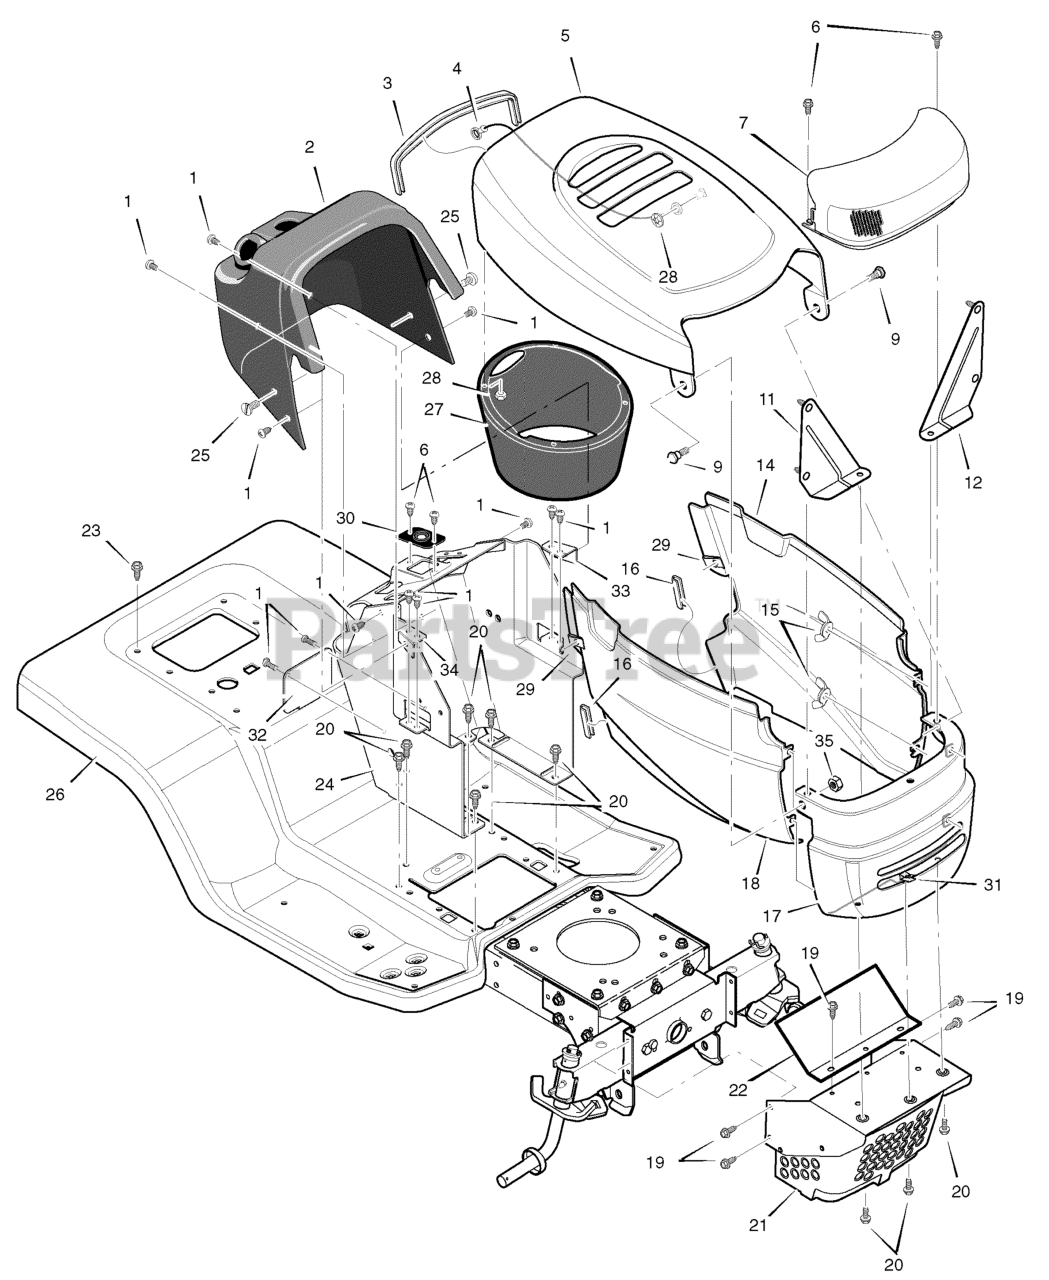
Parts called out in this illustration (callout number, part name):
1	Screw
3	Trim 2.23"
5	Hood Assembly
7	Lens & Reflector Assembly
9	Bolt, Shoulder
11	Brace, Right Grille Assembly
12	Brace, Left Grille Assembly
14	Panel, Left Side
15	Wingnut
16	Trim 0.39"
18	Panel, Right Side
19	Screw
20	Screw
21	Guard Assembly, Muffler
22	Shield, Upper Heat
23	Screw
25	Screw
26	Deck Seat
28	Retainer, Push
30	Bearing, Steering
32	Panel, Access
33	Bracket, Right Console
34	Bracket, Left Console
